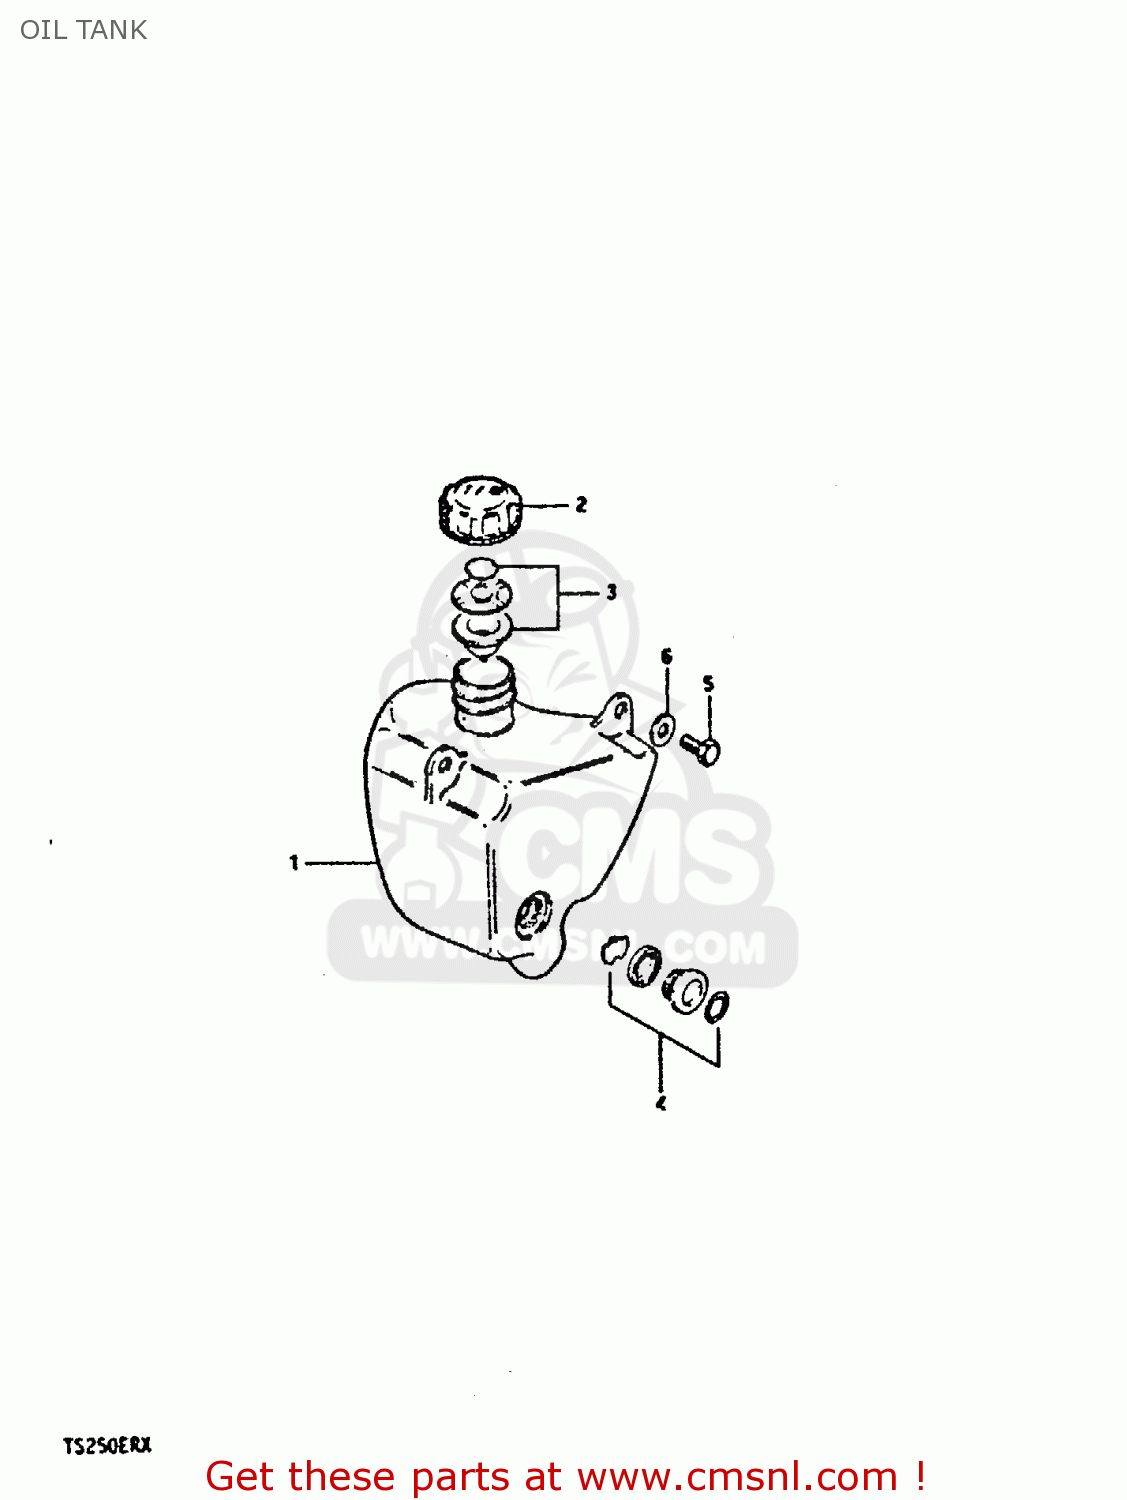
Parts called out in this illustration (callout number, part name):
1	TANK,OIL
2	CAP,OIL TANK
3	GASKET SET (NAS)
4	LENS SET,OIL LEVEL
5	BOLT, UPPER
6	WASHER
